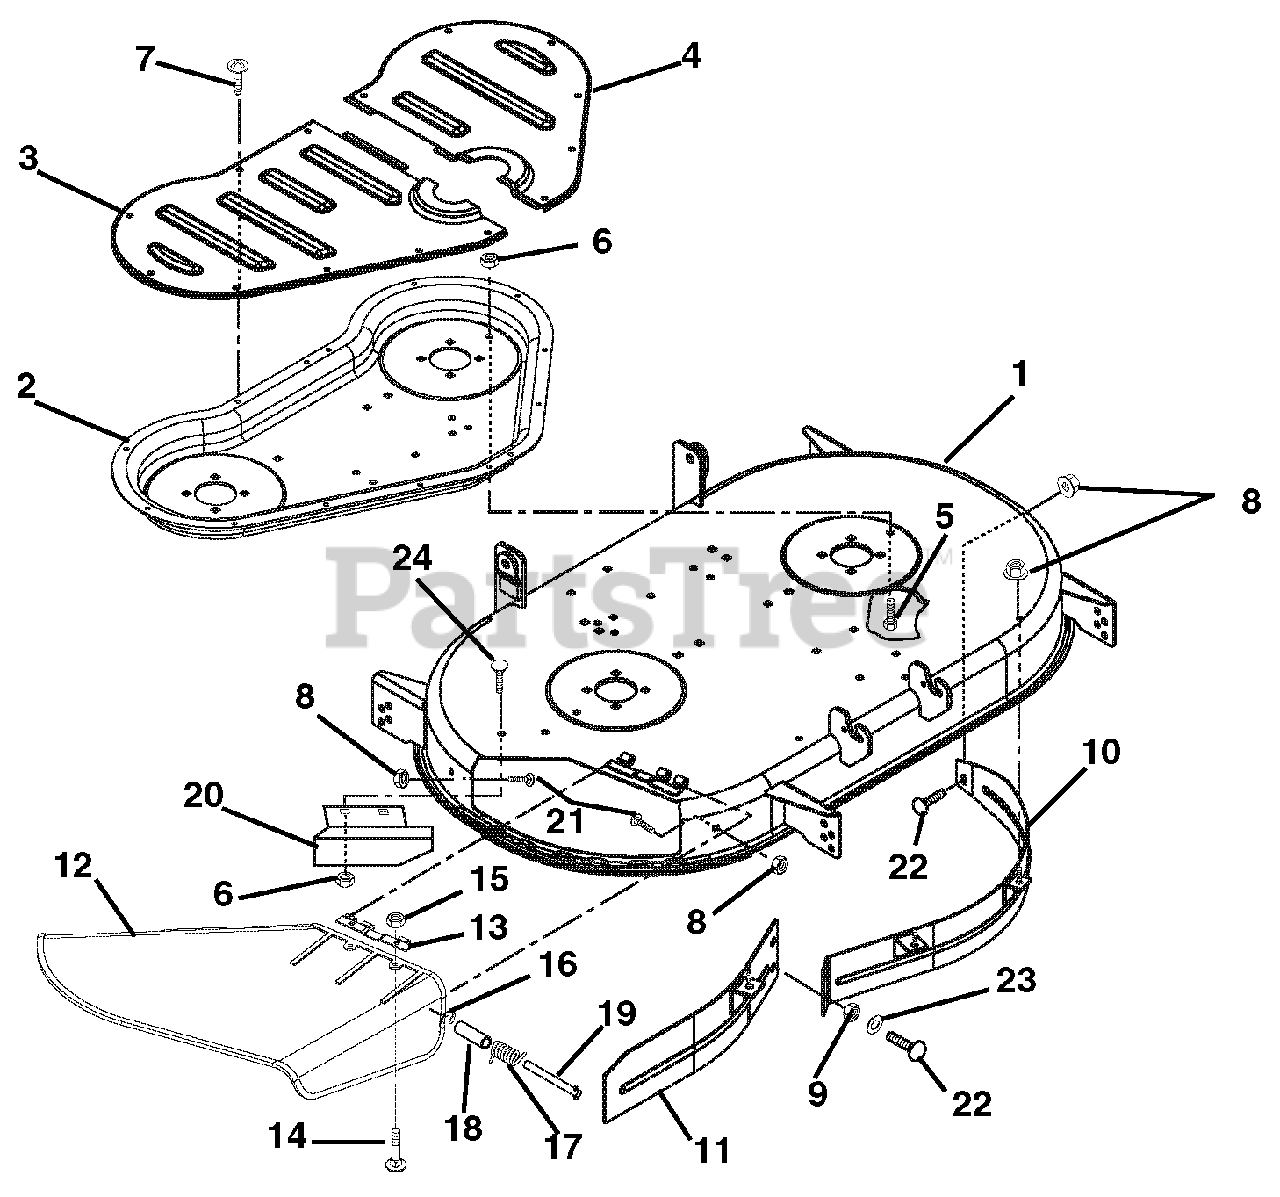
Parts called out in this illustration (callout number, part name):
1	Mower-42" Gravely ZT with Decals
1	Mower-42" Gravely ZT Assembly Complete
2	Reinforcement-Deck
3	Cover-Deck Reinforcement
4	Cover-Deck Reinforcement
5	Bolt-Hex .38-16 x 1.00
6	Nut-Locking-Top-Flange .38-16
7	Screw-Tapping Hex Washer Head Thread Rolling .31-18 x .50
8	Nut-Locking-Top-Flange .31-18
9	Nut-Lock-Center .31-18
10	Weldment-Baffle Upper Left Hand
11	Weldment-Baffle Upper Right Hand
12	Deflector-Chute 42"
13	Hinge-Plate
14	Bolt-Round Head Square Neck .25-20 x .75
15	Nut-Locking-Flange .250-20
16	Ring-Retaining-External .312 x .025
17	Spring-Torsion .095 x .50 x 1.00
18	Bushing-Sleeve
20	Deflector-Baffle
21	Bolt-Hex .31-18 x .75
22	Bolt-Round Head Square Neck .31-18 x .75 Grade 5
23	Washer-Flat-Steel .038 x .875 x .083
24	Bolt-Hex .38-16 x .75
